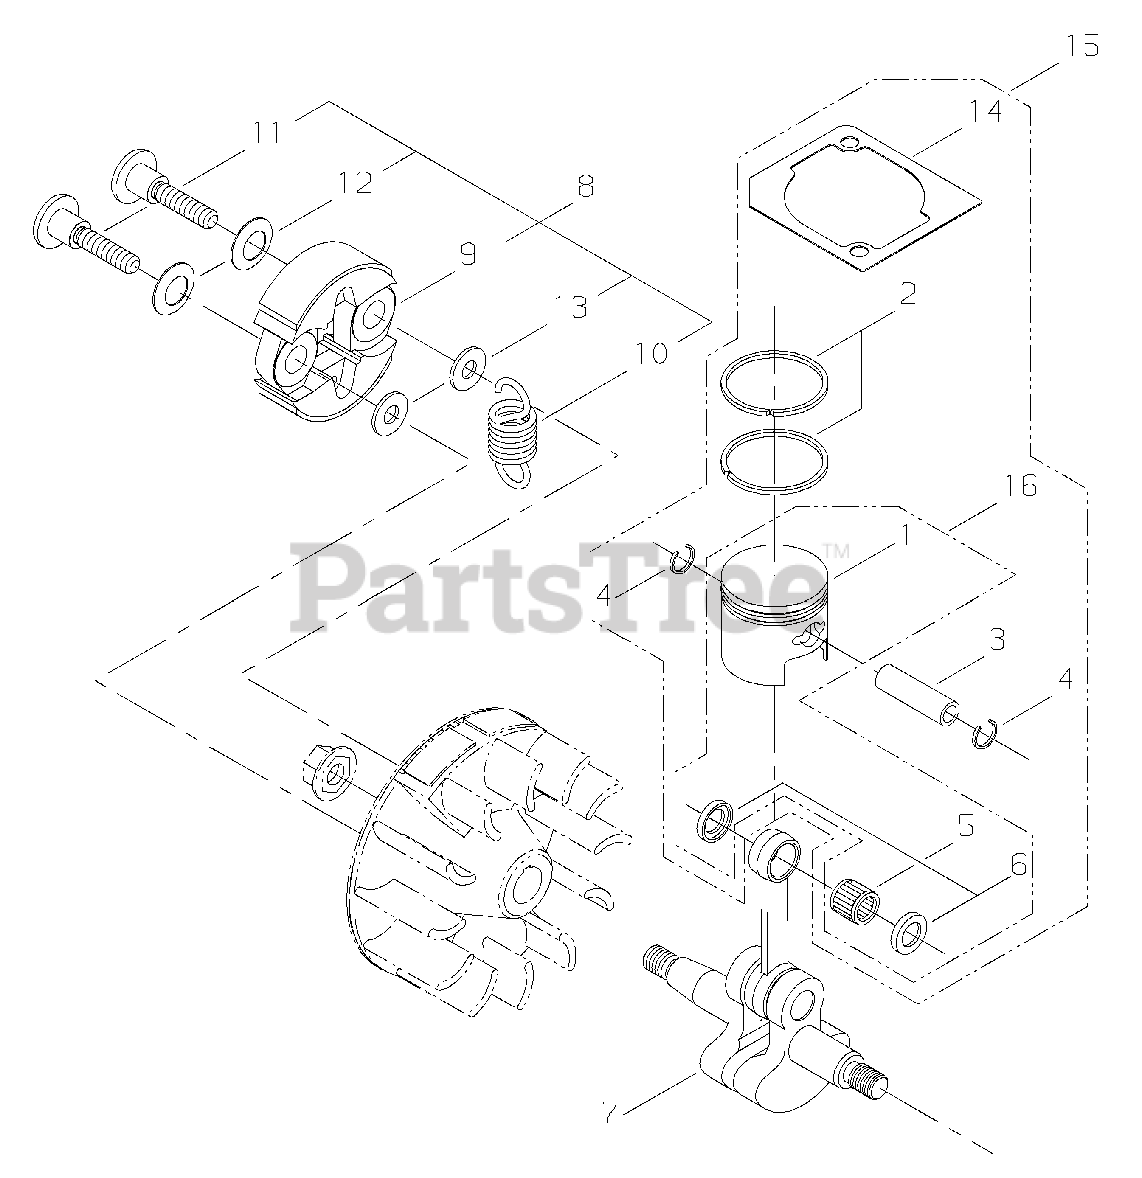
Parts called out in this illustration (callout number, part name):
1	PISTON
2	RING, PISTON
3	PIN, PISTON
3-15	PISTON KIT
4	RING, SNAP
5	BEARING, NEEDLE 8
6	WASHER, THRUST 8
7	CRANKSHAFT
8	CLUTCH ASSY
9	SHOE, CLUTCH
10	SPRING, CLUTCH
11	BOLT, CLUTCH
12	WASHER, SPRING
13	WASHER 6 MM
14	GASKET, CYLINDER
16	PISTON KIT
